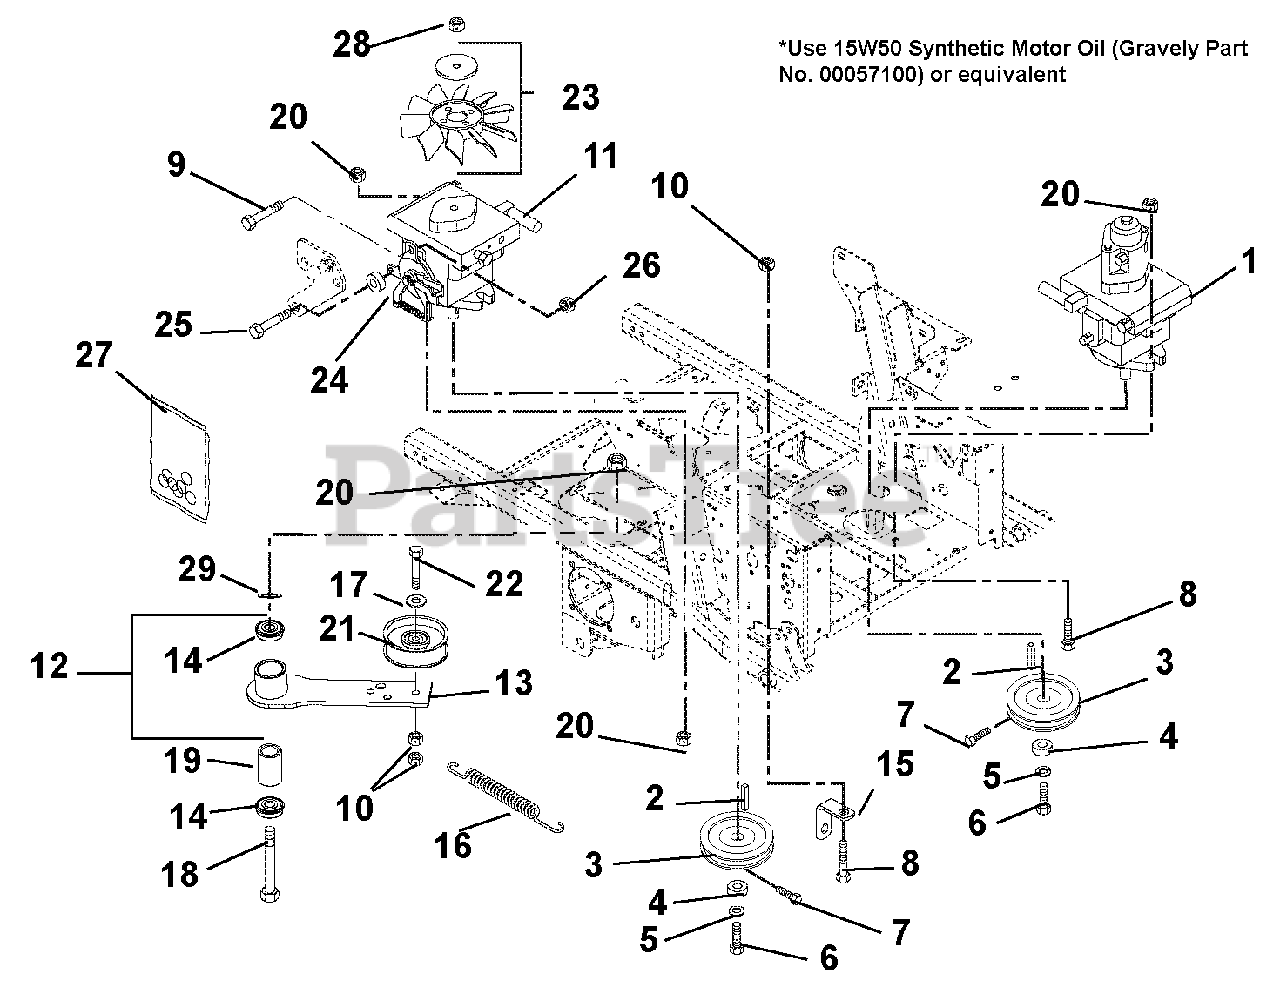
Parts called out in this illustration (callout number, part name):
1	Pump, Hydraulic with Auxiliary
2	Key, Square 5 x 5 x 30mm Plain
3	Sheave, Poly V .671 x 4.125
4	Washer, Flat Steel .281 x 1.000 x .063
5	Washer, Locking .25 x .062
6	Bolt, Hex M6 x 1.0 x 12 YZ EP30
7	Screw, Socket Head .25-20 x .50 YZ EP80
8	Bolt, Hex .50-13 x 1.50 Grade 5
9	Bolt, Hex .31-18 x .75 Grade 5
10	Nut, Locking Top Flange .38-16
11	Pump, Hydraulic BDP – 21 with Thru Fan (page 19)
12	Kit, Hydro Idler Arm
13	Weldment, Idler Arm Ground Drive
14	Bearing, Ball .50 x 1.38 x .438
15	Anchor, Spring Idler
16	Spring, Tension
17	Washer, Flat Steel .39 x .75 x.125
18	Bolt, Hex .50-13 x 3.50 Grade 5
19	Spacer .510 x .75 x 1.1485
20	Nut, Locking Top Flange .50-13
21	Idler, Flat 4.00 x .38
22	Bolt, Hex .38-16 x 2.25 Grade 5
23	Fan, Cooling
24	Spacer .318 x .43 x .375
25	Bolt, Hex .31-18 x 1.25 Grade 5
26	Nut, Locking Top Flange .31-18
27	Kit, Pump Seal (BDP – 21A) (One kit required for each pump)
28	Nut, Center Lock .31-24
29	Washer, Thrust .500 x .750 x .020
